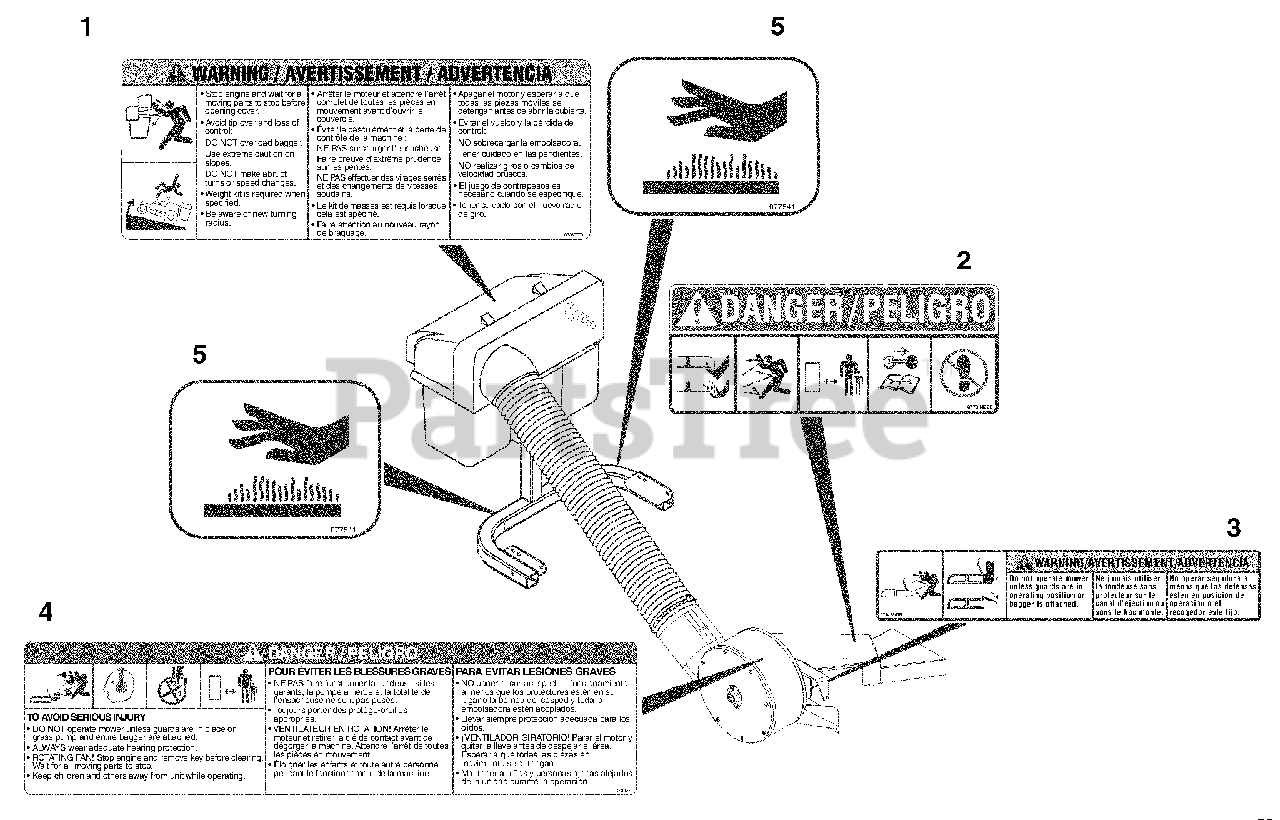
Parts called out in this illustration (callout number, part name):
1	DECAL, BAGGER COVER
2	DECAL, MOWER PAN DANGER
3	DECAL, WARNING
4	DECAL-CAUTION, GRASS PUMP
5	DECAL, HOT SURFACE
